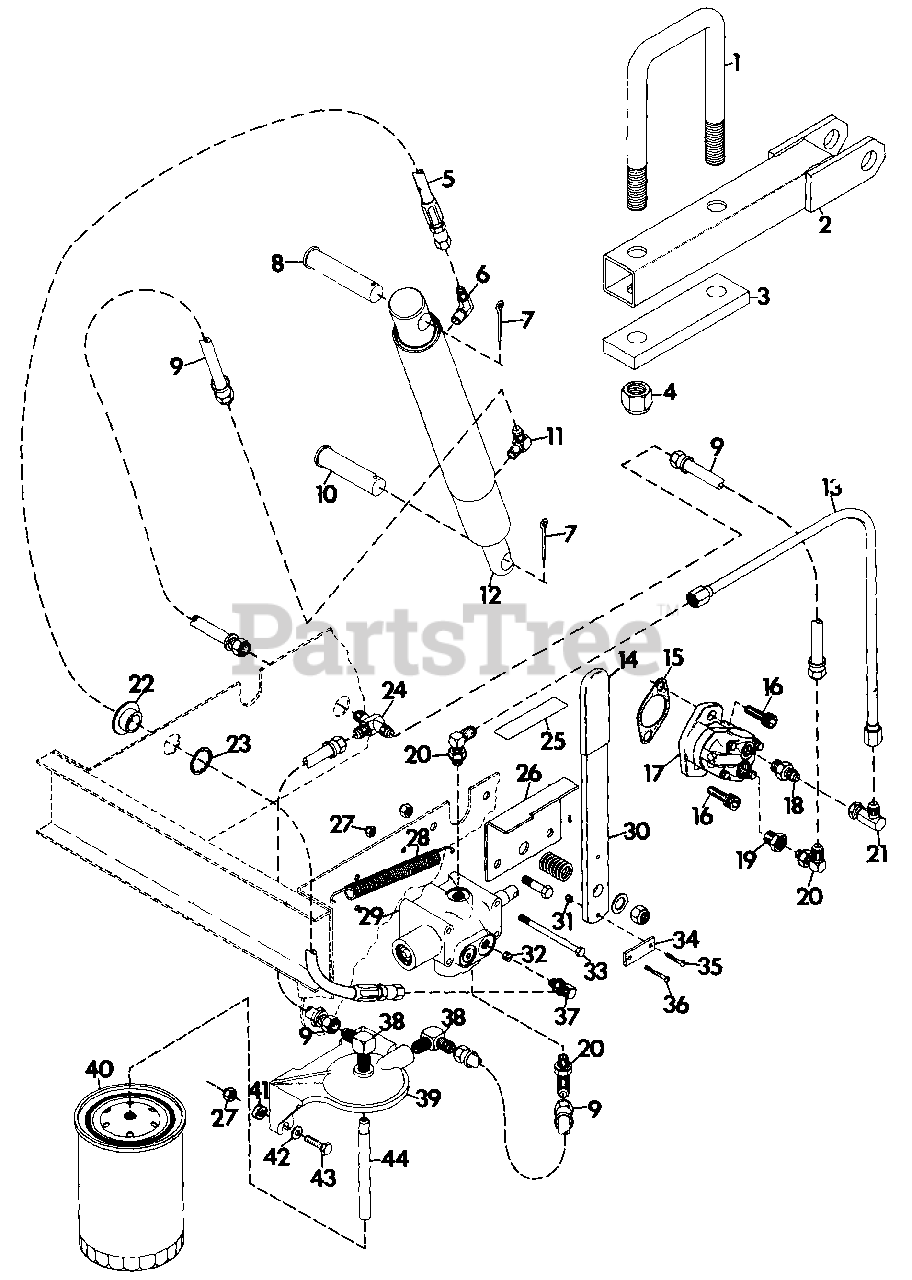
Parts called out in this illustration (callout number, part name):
1	U-BOLT
2	ARM, LIFT
3	PLATE, AXLE
4	NUT, LOCK 5/8-18
5	HOSE, HYDRAULIC
6	ADAPTOR
7	PIN, COTTER .125X1.25
8	PIN, CLEVIS
9	HOSE, HYDRAULIC
10	PIN, CLEVIS
11	ADAPTOR, HYDRAULIC
12	CYLINDER, HYDRAULIC
13	LINE, HYDRAULIC PUMP TO VALVE
14	GRIP, HANDLE
15	GASKET, COVER
16	SCREW, CAP 3/8-16 HEX SOCKET HEAD
17	PUMP, HYDRAULIC
18	ADAPTOR
19	BUSHING
20	ADAPTOR
21	ADAPTOR
22	BUSHING, NYLON .76X1X.6 FLANGE
23	RING, RETAINING INTERNAL TOOTH
24	ADAPTOR, TEE
25	DECAL, HYDRAULIC LIFT
26	BRACKET, LIFT
27	NUT, LOCK 1/4-20
28	SPRING, EXTENSION 5.5X.5X20 RATE
29	VALVE, CONTROL
30	LEVER, LIFT
31	NUT, LOCK 10-24
32	PLATE, FLOW RESTRICTION
33	BOLT, HEX 1/4-20X2.75
34	STRAP, VALVE
35	SCREW, MACHINE 10-24X.75 RD HD
36	SCREW, MACHINE 10-24X1.00 RD HD
37	ADAPTOR
38	ADAPTER
39	BRACKET, OIL FILTER
40	FILTER, SPIN-ON
41	SPACER
42	WASHER, FLAT .312X.734X.065
43	BOLT, HEX 1/4-20X1-1/4
44	TUBE, OIL PICKUP
